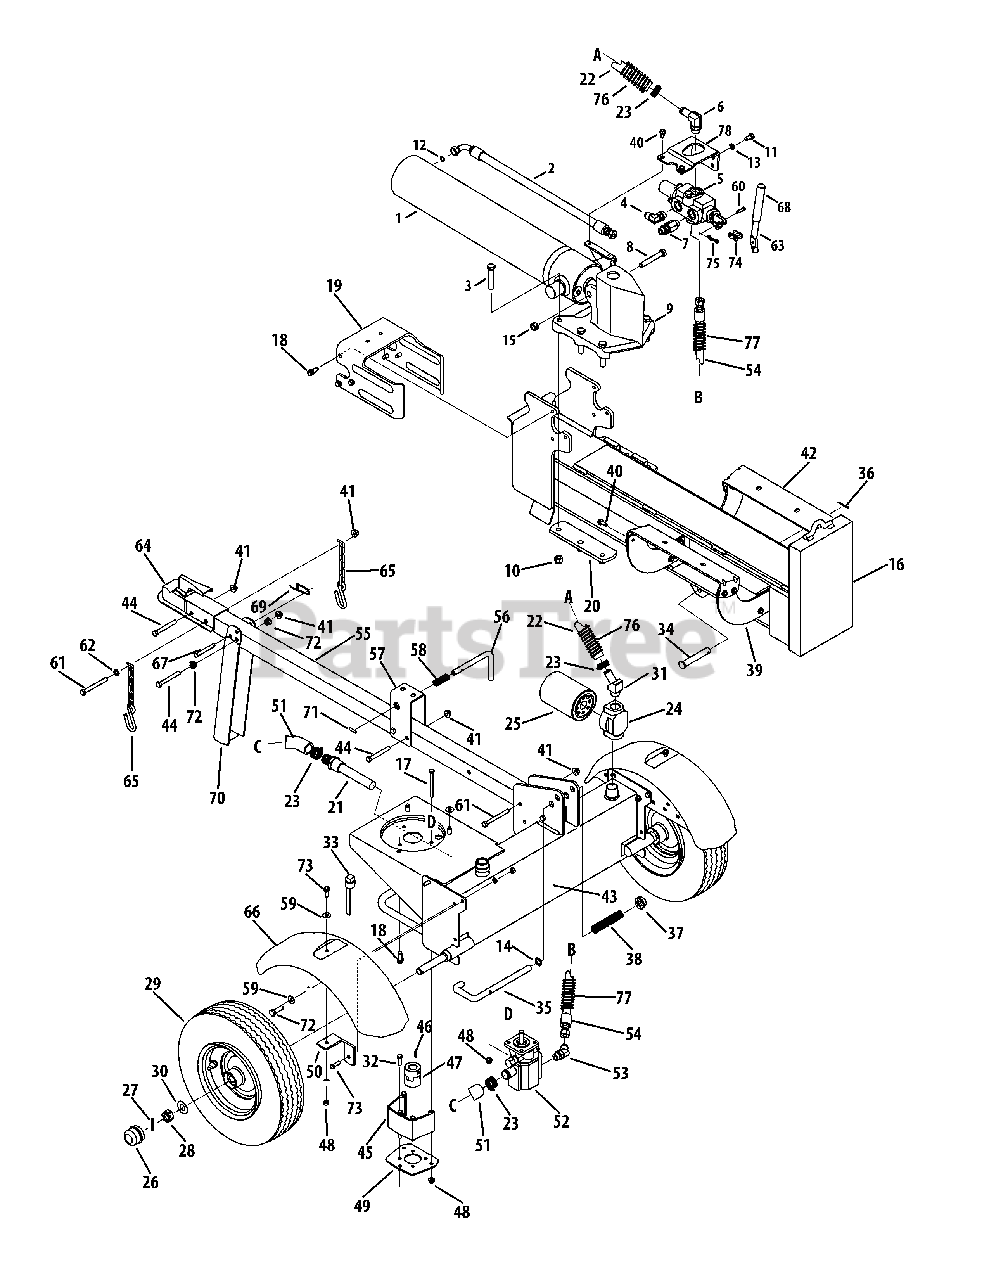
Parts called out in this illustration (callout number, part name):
1	Hydraulic Cylinder
2	Hydraulic Tube
3	Hex Cap Screw, 1/2-20 x 2.75
4	90 Degree Solid Adapter
5	Control Valve
6	Return Elbow
7	Nipple Pipe, 1/2-14
8	Hex Cap Screw, 1/2-13 x 3.25
9	Wedge Assembly
10	Hex Lock Nut, 1/2-20
11	Hex Cap Screw, 3/8-16 x .75
12	O-Ring, .419 ID x .070 Dia.
13	Lock Washer, 3/8
14	Flat Washer, .635 x.93 x.06
15	Hex Lock Nut, 1/2-13
16	Beam Assembly
17	Hex Screw, 5/16-18 x 3.25
18	Self Tapping Screw, 3/8-16 x 1.0
20	Back Plate
21	Inlet Filter
22	Return Hose, 3/4 x 44
23	Hose Clamp, 5/8
24	Filter Housing
25	Oil Filter
26	Hub Cap
27	Cotter Pin
28	Slotted Nut, 3/4-16
29	Complete Wheel Assembly
29	Dust Seal
29	Roller Bearing
30	Flat Washer, .760 x.500
31	Hydraulic Fitting, 1 1/16 Orb x .75
32	Hex Screw, 5/16-18 x 1.00
33	Vented Dipstick
34	Clevis Pin
35	Lock Rod
36	Cotter Pin
37	Push Cap
38	Compression Spring
39	Log Tray Bracket
40	Hex Washer Screw, 5/16-18 x .750
41	Flange Lock Nut, 3/8-16
43	Frame Assembly
44	Hex Bolt, 3/8-16 x 3
45	Coupling Shield
46	Square Key, 3/16" x .75
47	Coupling, .500
47	Coupling, .875
47	Spider Bushing
47	Set Screws
48	Flange Lock Nut, 5/16-18
49	Rear Coupling Support Bracket
50	Fender Mounting Bracket
51	Hose
52	Gear Pump
53	45 Degree Elbow Fitting
54	High Pressure Hydraulic Hose
55	Tongue Assembly
56	Latch Rod
58	Compression Spring
59	Flat Washer
60	Clevis Pin
61	Hex Cap Screw, 3/8-16 x 3.50
62	Flat Washer, .375 x.738 x.063
63	Hydraulic Valve Control
64	Hitch Coupling Assembly
66	Fender
67	Clevis Pin
69	Spring Pin
70	Jack Stand
71	Spiral Pin
72	Plastic Bushing, .380 ID
73	Self-Tapping Screw, 5/16-18 x 1.00
74	Valve Handle Link
75	Cotter Pin, Bow Tie
76	Hose Guard, 44"
77	Hose Guard, 48"
78	Outer Valve Bracket
